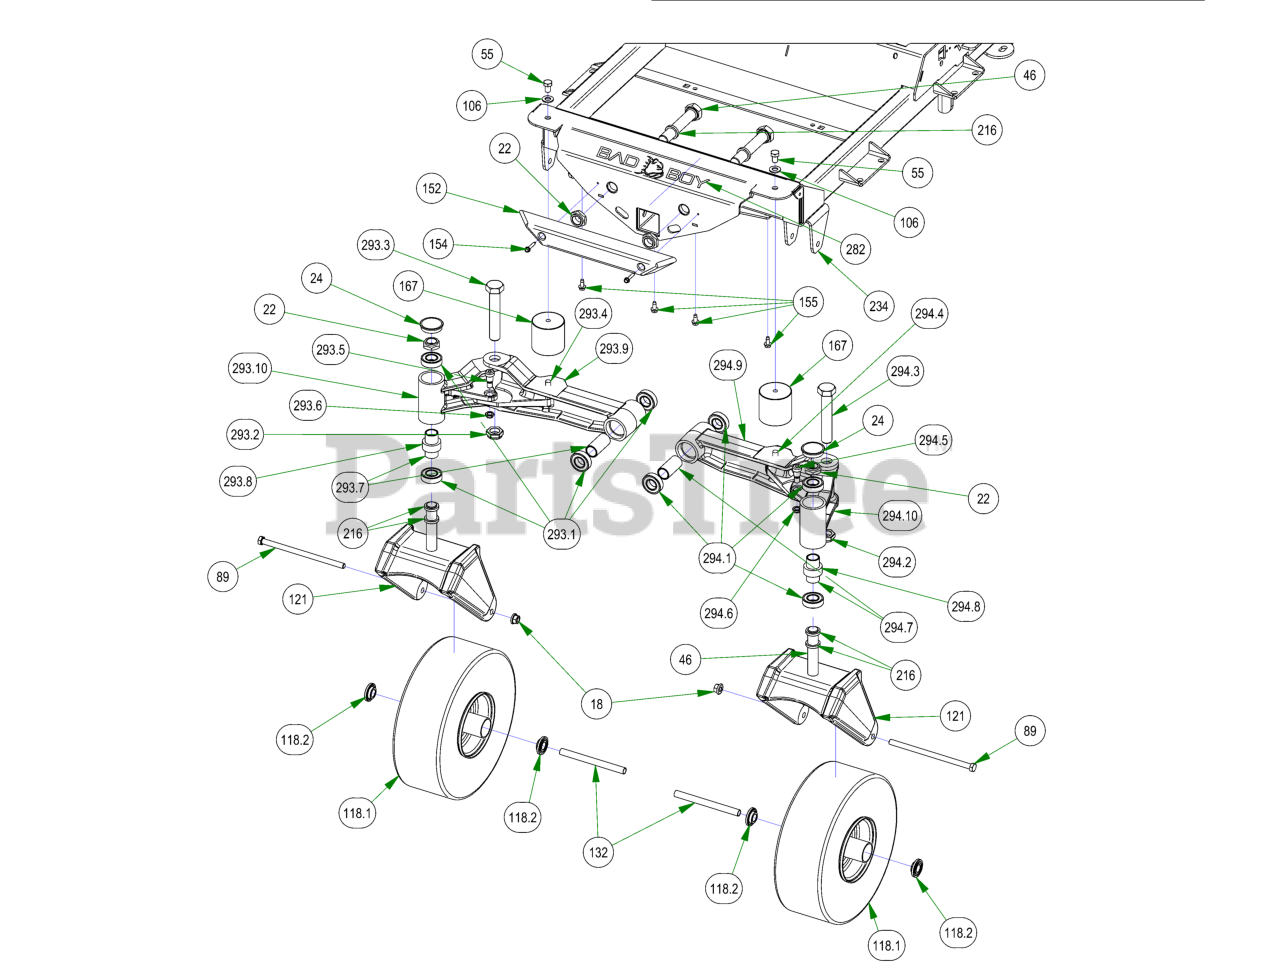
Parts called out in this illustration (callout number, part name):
18	1/2-13 NYLON INSERT FLANGE LOCKNUT ZINC
22	1"-14 NYLON INSERT JAM LOCKNUT ZINC
24	2017 Bearing Cover
46	1"-14 X 5-1/2 HEX CAP SCREW (GR.8) ZINC YELLOW
55	1/2-13 X 3/4 HEX CAP SCREW (GR.5) ZINC
89	1/2-13 X 9 HEX CAP SCREW (GR.5) ZINC
106	1/2 SAE FLAT WASHER (1-1/16" OD) GR.8 ZINC YELLOW
118	2019 15x6.00-6 Non Pneumatic Black Front Assembly
118.2	1-3/4" Bearing-Large Bore Front Rim
121	2020 R Series Cast Front Fork
132	Front Wheel Spanner
152	2017 XP Bumper
154	1/4-14 X 1-1/2 HEX WASHER UNSLOT TEK/3 ZINC
155	5/16-18 X 3/4 HEX WASHER SLOT (F) TCS ZINC
167	Vibration Mount-Blue Dot
216	1.02 ID X 1.38 OD X .250 THK SPACER ZINC
234	2022 Horizontal Diesel Frame
282	Flying Bulldog Front Bumper Decal
285	Independetly Articulating Front Suspension Arms Patent Decal
293	2022 61/72 Rogue/Renegade Front Suspension Asy RH
293.1	1641 BEARING W/2 CONTACT RUBBER SEALS
293.2	1" Fine Thread 1/2 Nylock Nut
293.3	1"-14 X 5-1/2 HEX CAP SCREW (GR.8) ZINC YELLOW
293.4	1/2-13 x 1" Stud
293.5	5/8 X 5/8 SOCKET SHOULDER BOLT ZINC YELLOW
293.6	1/2-13 NYLON INSERT JAM LOCKNUT ZINC
293.7	2016 Front Bearing Spacer
293.8	Rubber Stabilizer (Front Forks) [R series]
293.9	INNER RH FRONT AXLE
293.10	OUTER FRONT ARM RH
294	2022 61/72 Rogue/Renegade Front Suspension Asy LH
294.1	1641 BEARING W/2 CONTACT RUBBER SEALS
294.2	1" Fine Thread 1/2 Nylock Nut
294.3	1"-14 X 5-1/2 HEX CAP SCREW (GR.8) ZINC YELLOW
294.4	1/2-13 x 1" Stud
294.5	5/8 X 5/8 SOCKET SHOULDER BOLT ZINC YELLOW
294.6	1/2-13 NYLON INSERT JAM LOCKNUT ZINC
294.7	2016 Front Bearing Spacer
294.8	Rubber Stabilizer (Front Forks) [R series]
294.9	INNER FRONT ARM LH
294.10	CAST OUTER ARM LH
